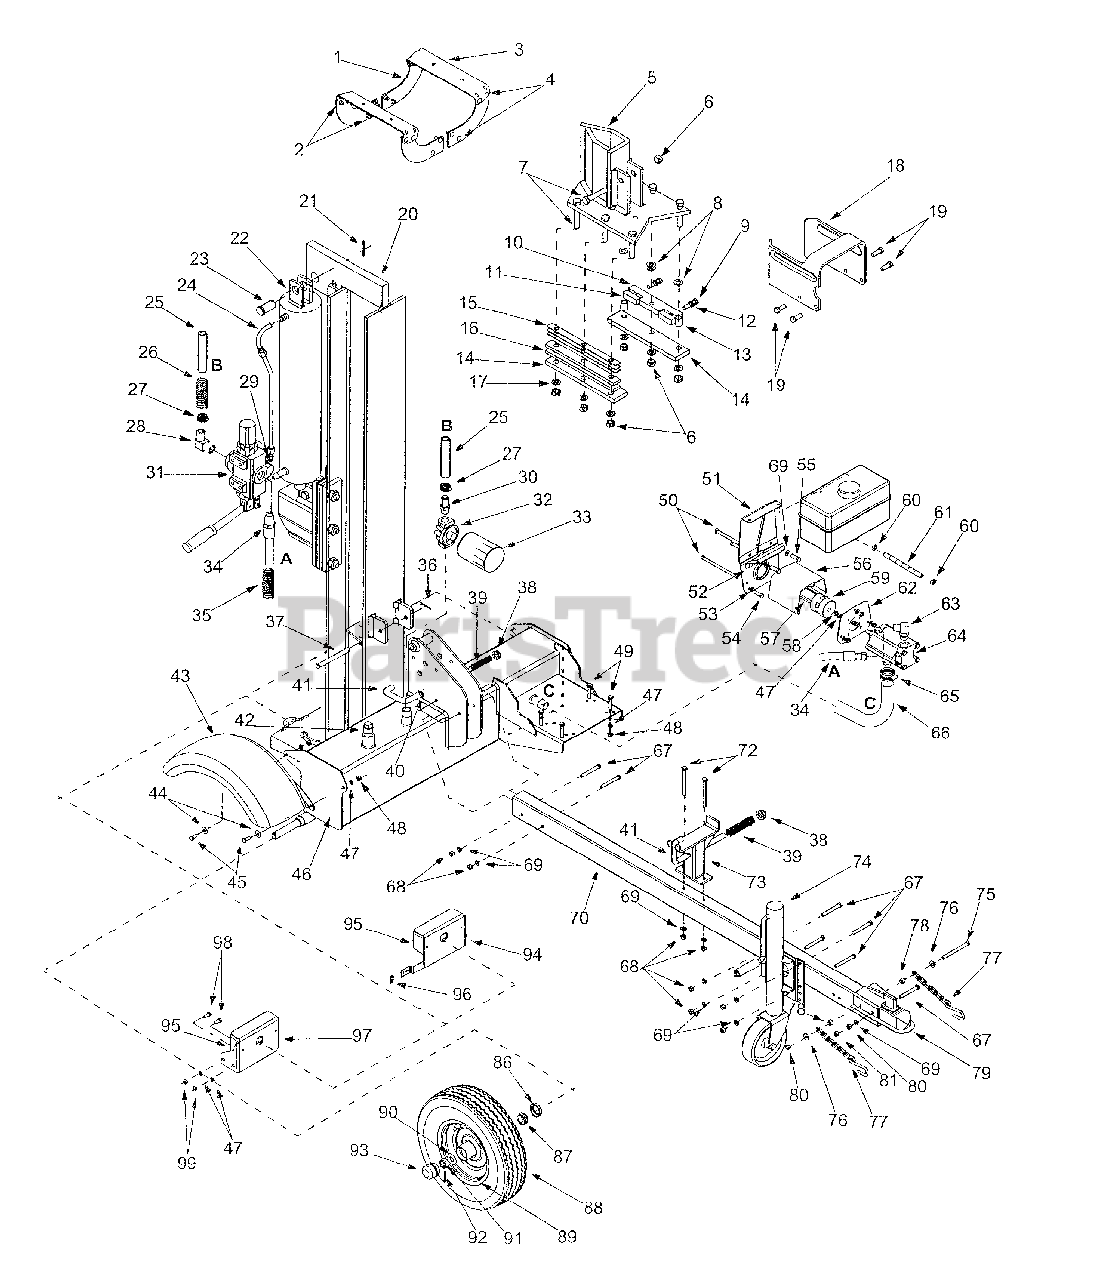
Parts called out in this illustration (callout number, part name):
4	Carriage Bolt 3/8-16 x 1.0
6	Lock Nut 1/2-20
7	Hex Cap Screw 1/2-20 x 2.75
8	Flat Washer .531 ID x .93 OD
9	Hex Cap Screw 3/8-24 x 1.5
11	Adjustable Gib
12	Hex Jam Nut 3/8-24
13	Spacer
17	Lock Washer 1/2
19	Hex Cap Screw 3/8-16 x 1.0
22	Kit Seal 5.0" for Best Metals cylinder 718-0313
22	Hydraulic Cylinder
22	Kit Seal 5.0" for XINGHUI cylinder 718-0313A
22	Kit Seal 5.0" for ENERGY cylinder 718-0313A
23	Clevis Pin
24	Hydraulic Tube
25	Return Hose 3/4" ID x 44" Lg.
26	Hose Guard
27	Hose Clamp 5/8"
28	Return Elbow
29	90 Degree Solid Male Adapter
30	3/4" Hose Adapter
32	Filter Housing
33	Oil Filter
34	High Pressure Hydraulic Hose
35	Hose Guard
36	Cotter Pin 1/8"
37	Hinge Pin 1/2 x 4.8" Lg.
39	Compression Spring 4"
40	Flat Washer .635 ID x .93 OD
41	Locking Rod
42	Pipe Plug
45	Hex Cap Screw 5/16-24 x .75
46	Frame Assembly 7.0 Gal
47	Lock Washer 5/16
48	Hex Nut 5/16-24
49	Hex Cap Screw 5/16-24 x 1.
50	Hex Cap Screw 5/16-24 x 5.
51	Fuel Tank Mounting Bracket
52	Fuel Tank Mounting Bracket
53	Lock Washer 5/16
54	Hex Cap Screw 5/16-24 x 1.0
55	Hex Cap Screw 3/8-16 x 1.0
56	Shoulder Spacer
57	Key, 1/4 x 2.00
57	Key, 3/16 x .75
58	Hex Screw 5/16
59	Flexible Coupling, 1.00 x .4375
60	Hose Clamp
61	Fuel Line Hose
63	Adapter 7/8-14
64	Gear Pump, Hyd (16 GPM)
64	Pump Kit
64	Gear Pump, Hyd (15 GPM)
65	Hose Clamp
66	Suction Hose
67	Hex Cap Screw 3/8-16 x 3.0
68	Hex Nut 3/8-16
69	Lock Washer 3/8
72	Hex Cap Screw 3/8-16 x 4.0
75	Hex Cap Screw 3/8-16 x 4.25
76	Flat Washer .385 ID x .870 OD
77	Chain
79	Hitch Coupler
80	Lock Nut 3/8-16
81	Hex Jam Nut 3/8-16
86	Bearing Seal
87	Bearing Cone
88	Wheel Assembly
89	Rim Assembly
90	Flat Washer .76" ID x 1.5" OD
91	Slotted Nut 3/4-16
92	Cotter Pin 5/32" x 1-1/4" Lg.
96	Nut 1/4-20
99	Hex Nut 5/16-24
